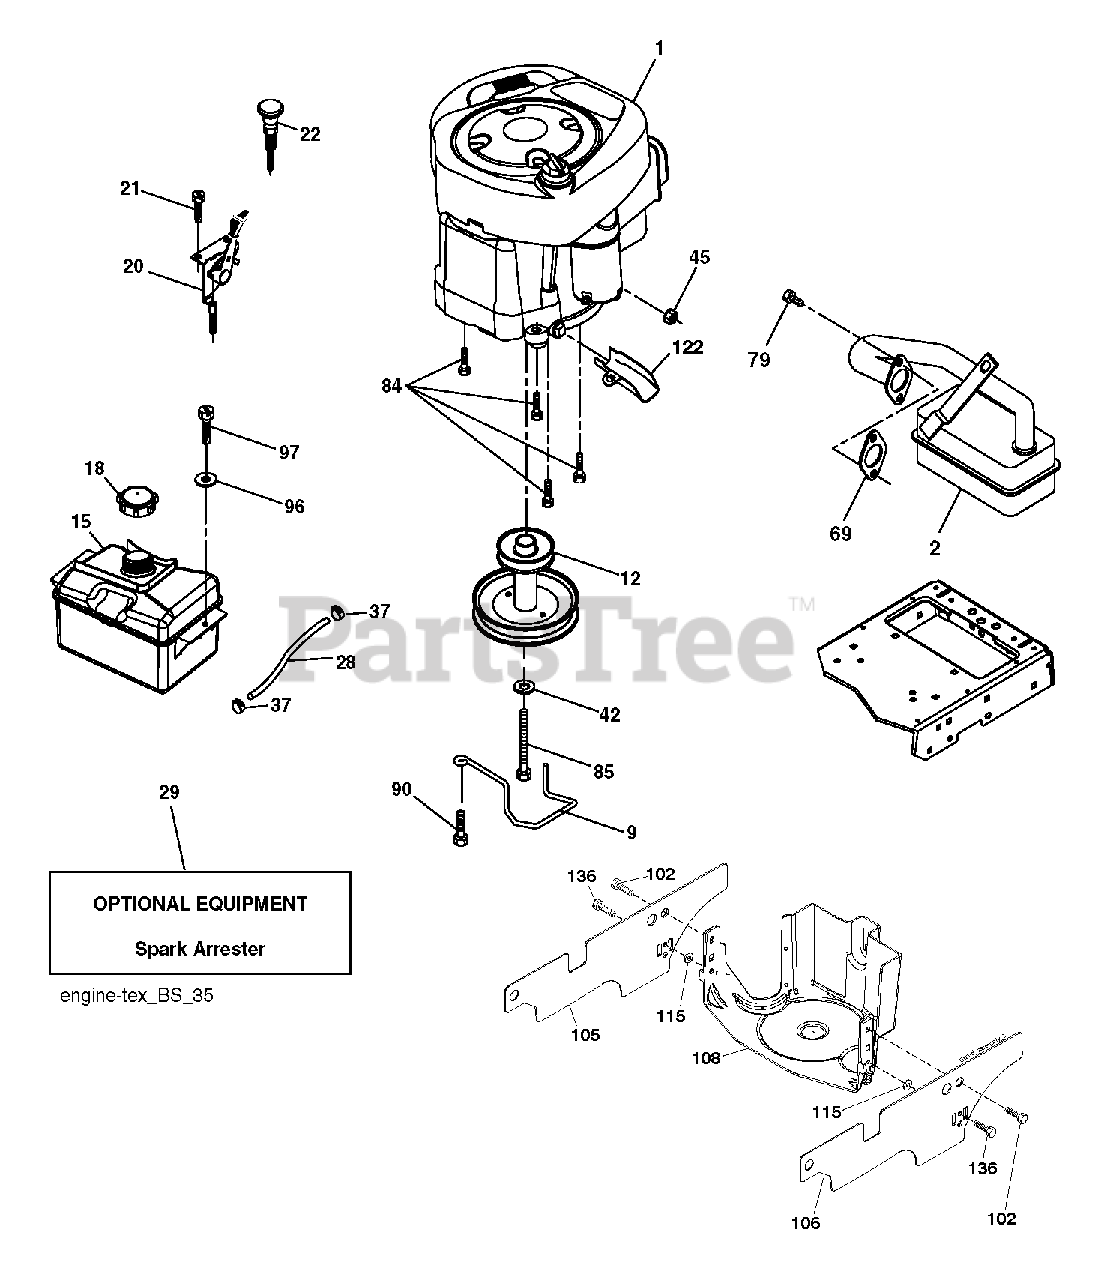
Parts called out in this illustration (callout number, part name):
9	KEEPER.BELT.ENGINE
12	PULLEY ENGINE
18	CAP ASM.FUEL.2.25"FR.
20	CONTROL.TH/CK.C.
21	SCREW.#10 X 0.750.BOS THREAD
28	LINE.FUEL.20
29	ARRESTER SPARK (OPTIONAL)
37	HOSE CLAMP
42	LOCKWASHER
45	NUT
69	REPL BY 532 27 22-93
79	SCREW.SOCKET HD.5/16-1
84	SCREW.3/8-16
85	BOLT HEX 7/16-20X4-1/4"
90	SCREW 3/8-16X1
97	SCREW HEXWSHR 1/4-20X3/4
102	SCREW
115	PALNUT 1/4
122	EXTENSION DRAIN OIL
136	SCREW.1/4-20X5/8
